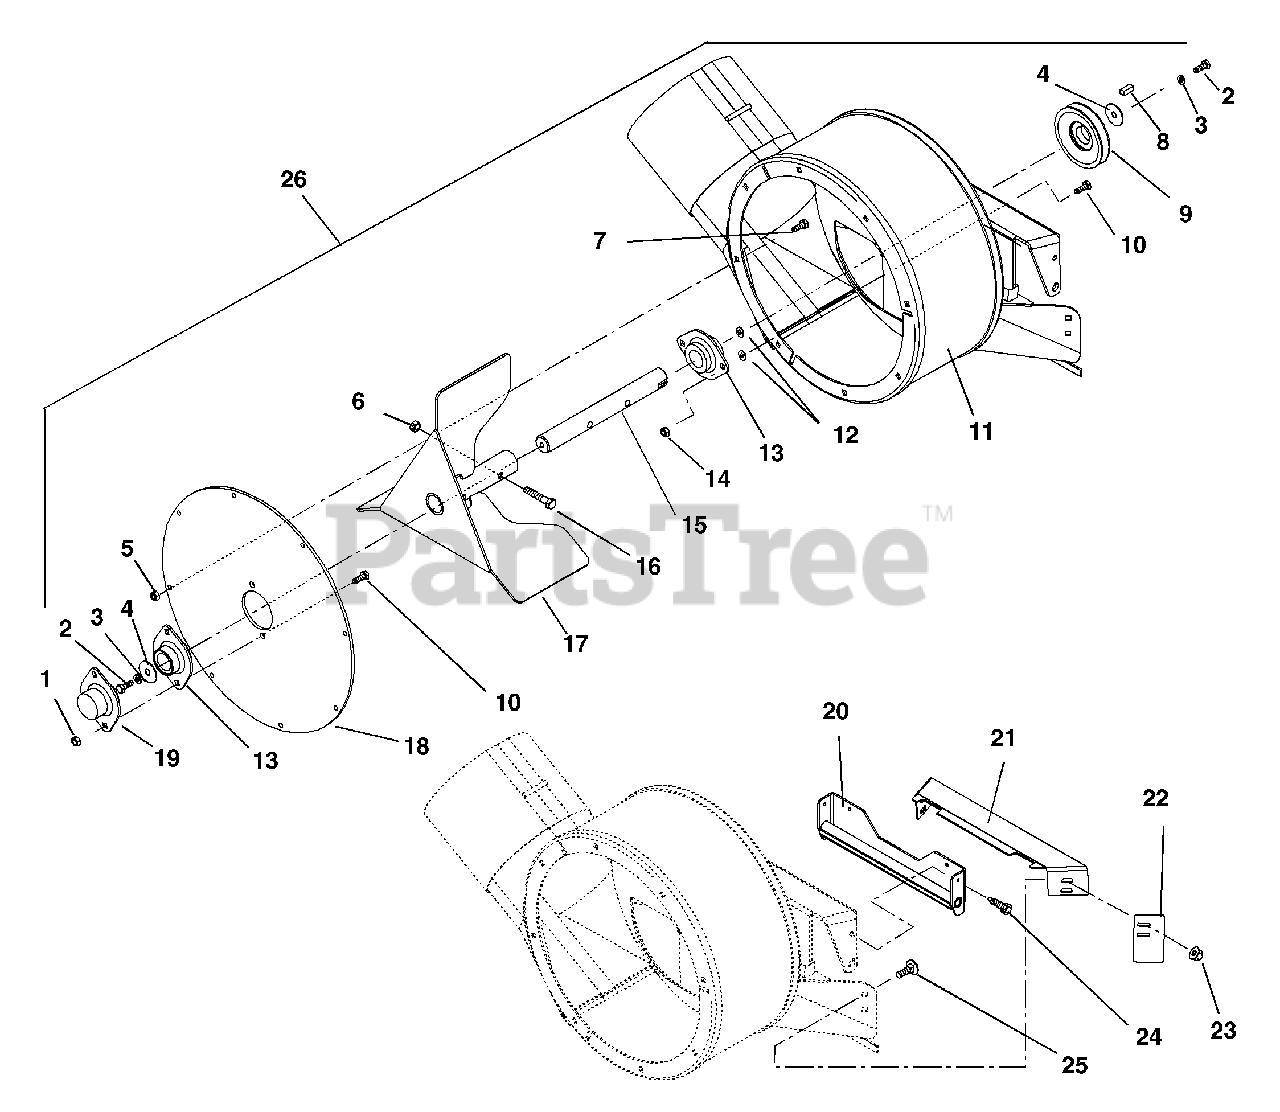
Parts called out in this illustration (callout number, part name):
1	Nut-Locking-Nylon .312-18
2	Bolt-Hex .25-20 x .75 Grade 5
3	Washer-Locking .25 x .062 Regular
4	Washer-Flat-Steel .265 x 1.370 x .179
5	Nut-Locking-Top-Flange .25-20
6	Nut-Locking-Center .31-18
7	Bolt-Round Head Square Neck .25-20 x .50
8	Key-Square .25 x .38 x .25
9	Pulley-Driven 3.50 Dia.
10	Bolt-Hex .31-18 x 1.00 Grade 5
11	Weldment, Blower Housing
12	Washer-Flat-Steel .312 x .734 x .06
13	Bearing-2 Bolt x 1.00 Shaft
14	Nut-Locking-Top-Flange .31-18
15	Shaft-Impeller
16	Bolt-Hex .31-18 x 1.75 Grade 5
17	Impeller Complete
18	Cover-Bearing Support
19	Cover-Bearing
20	Weldment, Blower Mount
21	Guard, Pump Inlet
22	Bar, Extension
23	Nut-Locking-Top-Flange .25-20
24	Screw-Tapping .25-20 x .50 Hex Washer Head Thread Rolling
25	Bolt-Round Head Square Neck .25-20 x .75 Grade 5
26	Assembly, Blower Housing
